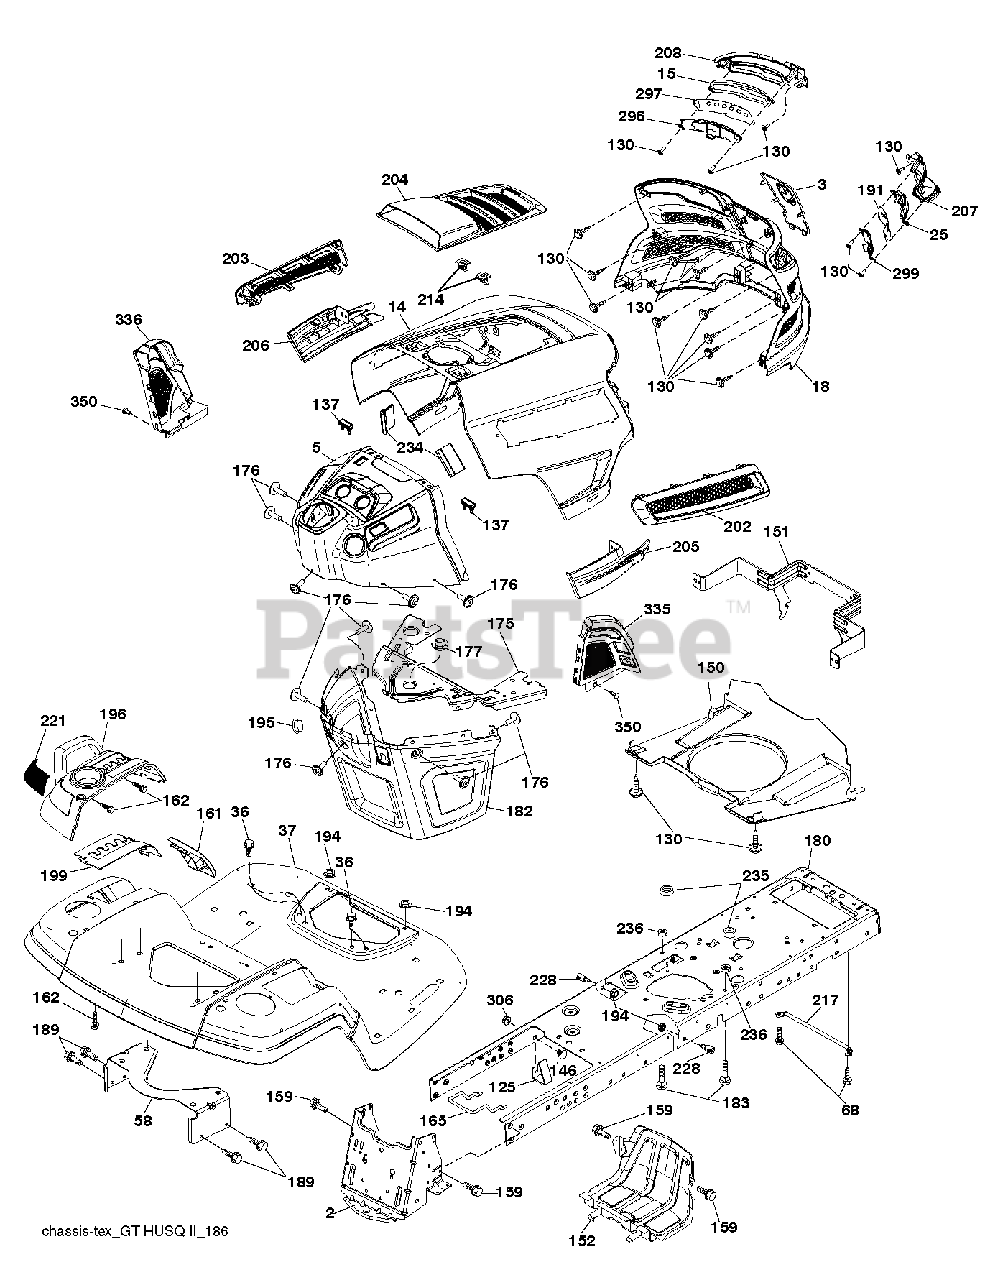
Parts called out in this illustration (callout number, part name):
2	DRAWBAR.STGT
3	APPLIQUE.SUBASM.GT.HUSQ.II
5	DASH
14	HOOD.ASM.HUSQVARNA.GT.TEX.ORAN
15	LED LIGHT.LH
18	GRILLE SUBASM.GT.II.LOW.HDLGHT
25	LENS.RH
36	SCREW 5/16"
37	FENDER.PNT.TX.GT.CH/FW/DL.HUSQ
58	BRKT.SUPPORT.FNDR/TANK
68	SCREW LT
125	CLIP.FUEL.LINE
130	SCREW.#10 X 0.750.BOS
137	BUMPER DASH
146	BOLT.RDHD.SHT.SQNK.3/8-16X5/8
150	AIR DUCT.GTV2(1.66"RING HEIGHT
151	BRACKET.PIVOT.HOOD.GT.HUSQ.II
152	SHIELD.BROWNING.PNT.GT.V2
159	SCREW, 3/8-16X3/4
161	CONSOLE.WINDOW.FUEL.HUSQ.GT
162	SCREW.HI-LO.CONSOLE
165	SUPPORT.TANK.REAR.B/TE
175	PLATE.CROSSMEMBER.HUSQ
176	SCREW.#10-24X5/8.RN.QU
177	BUSHING STEERING
180	CHASSIS.TEX.BOLTED
182	DASH.LOWER.COMMON.12V.ADAPTOR
183	BOLT.5/16-18X1-1/4 FULL THD
189	SCREW
191	INSERT INFLECT.RH
194	NUT LOCK HEX FLANGE 5/16-18
195	PLUG.HOLE.DASH.LOWER.12V.BLK
196	SUBASM.CONSOLE.HUSQ.GT.DECKLFT
199	PLATE.DECK.LIFT.HUSQVARNA.GT
202	VENT.SIDE.RH.GT.HUSQ.II.
203	VENT.SIDE.LH.GT.HUSQ.II.498
204	VENT.TOP.ASM.HUSQ.GT2
205	SIDE.TRIM.RH.GT.HUSQ.II
206	SIDE.TRIM.LH.GT.HUSQ.II.GRAY
207	BEZEL GT2 LED RH W/ LOWER.ATT
208	BEZEL GT2 LED LH W/ LOWER ATT
214	CLIP.RETAINER.TINNER.
217	ROD.PIVOT.HOOD
221	REFLECTOR.LH.TEX GT HU
228	STUD.FASTNER.W/ANTI-ROTATE
234	BUMPER.HOOD.TEX.HUSQVARNA
235	SPACER FENDER
236	NUT.CENTERLOCK.5/16-
296	LED LIGHT.LH
297	INSERT REFECT LH
299	LED LIGHT.RH
306	NUT LOCK FLG 3/8-16 UNC
335	COVER.LOWER.DASH.RH.BLACK
336	COVER-LH.LOWER.DASH.GT2.BLACK
350	CLIP.X-MAS.TREE
